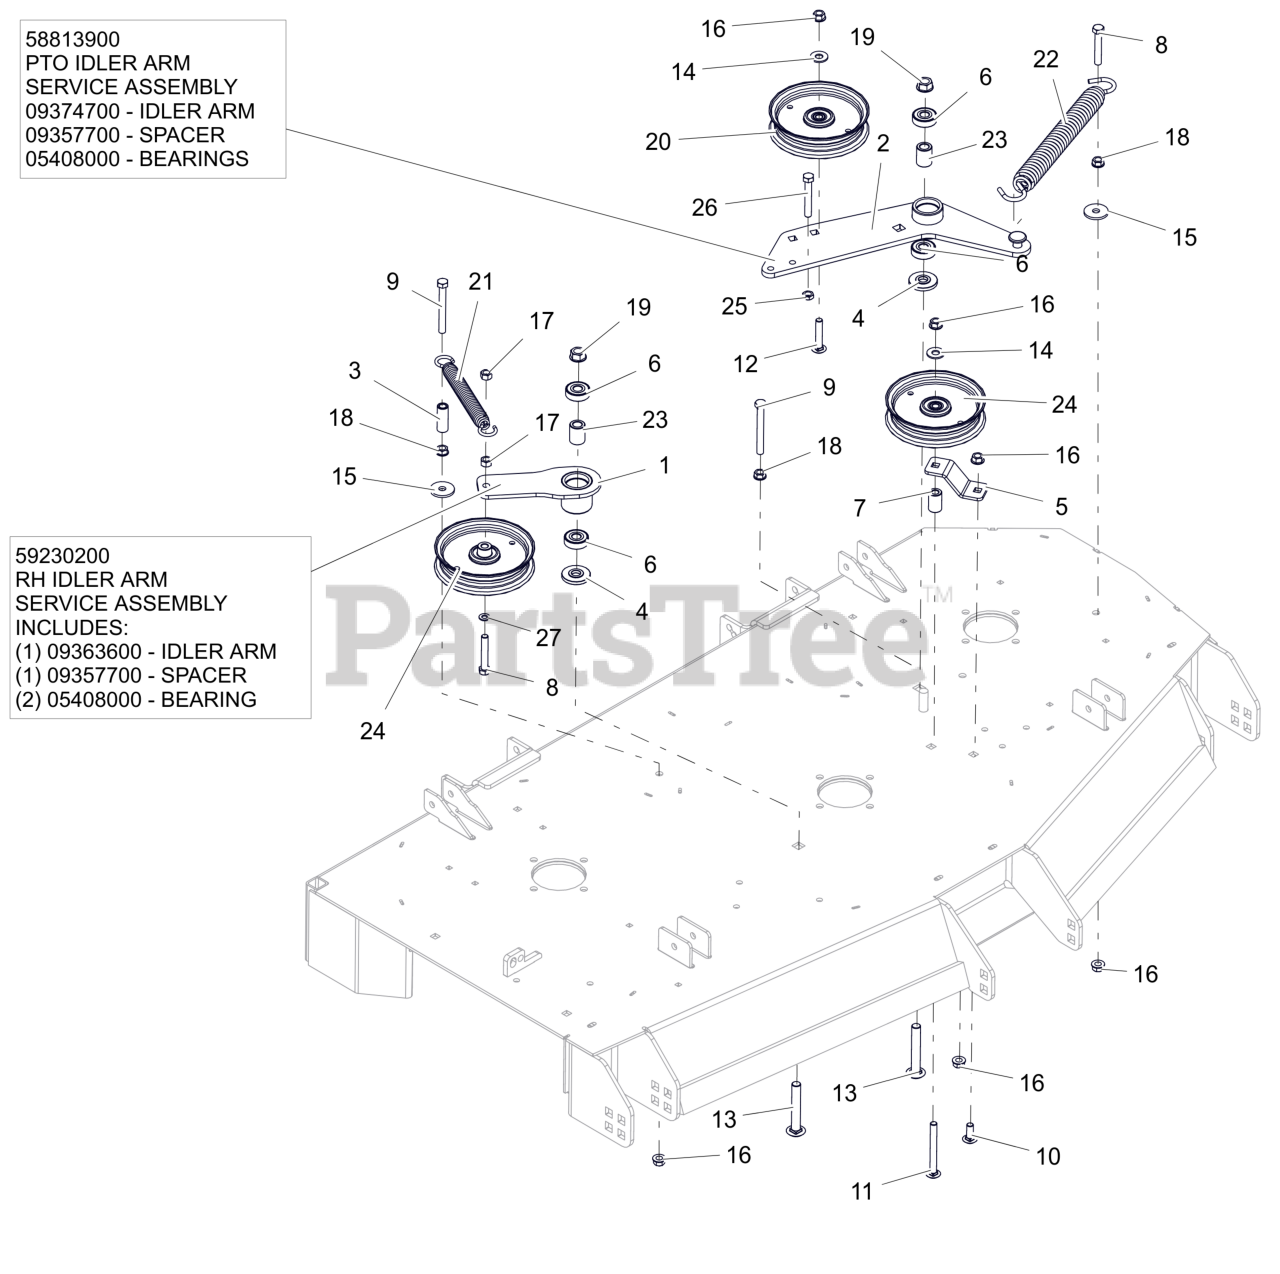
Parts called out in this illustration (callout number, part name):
1	WLDMT, DECK RH IDLER ARM
1	RH IDLER ARM
1	SPACER .510 X .867 X 1.1485
1	BRG-BALL .500X1.38X.437
2	WLDMT, IDLER ARM PT660
2	PTO IDLER ARM
2	SPACER .510 X .867 X 1.1485
2	BRG-BALL .500X1.38X.437
3	SPACER, .375IDX.625ODX1.66 PM
4	SPACER, IDLER ARM
5	PTO FIXED IDLER MTG BRKT -RED
6	BRG-BALL .500X1.38X.437
7	BUSHING, SLV .380X.750X1.190
8	BLT,HEX .38-16X2.25 G5 ZCC
9	BLT, HEX .38-16X3.25 G5 ZCC
10	BLT,RHSSN .38-16X1.00 G5 ZCC
11	BLT,RHSSN .38-16X3.50 G5 ZCC
12	BLT,RHSSN.375-16X2.00 G5 ZCC
13	BTL,RHSSN .500-13 X 3.25 G5 ZCC
14	WSHR,FLT .438X1.00X.083 ZCC
15	WSHR,FLT .406X1.375X.135 ZCC
16	NUT-LK-CTR-FLG .375-16 GF ZCC
17	NUT-LK-CTR .38-16 ZC120
18	NUT, SPNLK-FLG .38-16 G5 ZCC
19	NUT-LK-CTR-FLG .500-13 GG ZCC
20	PULLEY, FLAT IDLER .500 X .375 W/BRG
21	SPRING- EXTENSION
22	SPRING, EXTENSION
23	SPACER .510 X .867 X 1.1485
24	IDLER- FLAT - 5.00" X .75"
25	NUT-JAM .375-16 G2 ZCC
26	BLT, HEX .38-16X2.50 G5 ZCC
27	WSHR,FLT .323X.625X.062 ZCC
